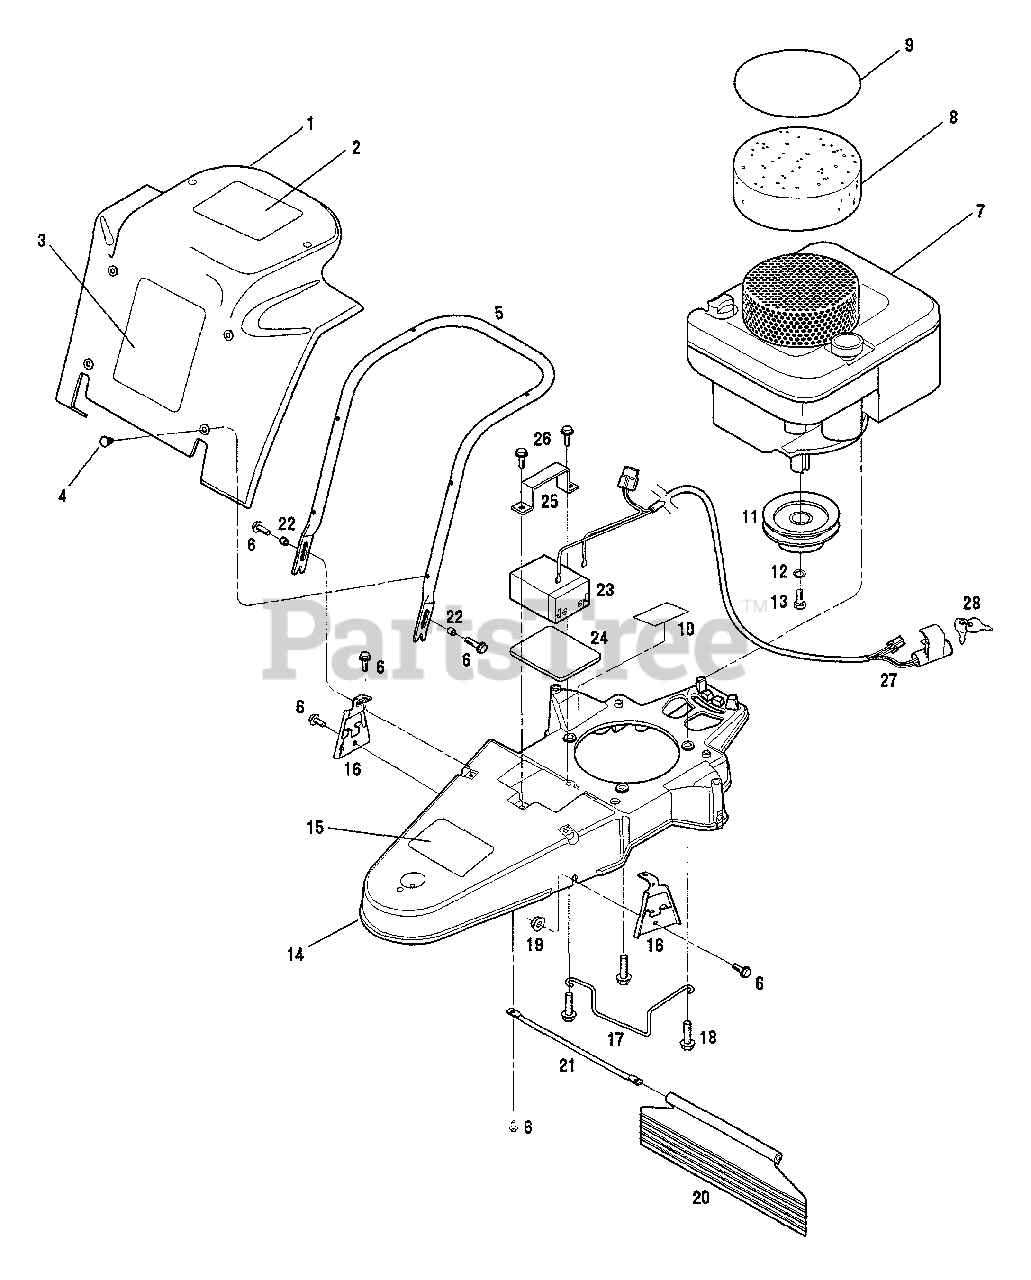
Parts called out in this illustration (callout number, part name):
1	Debris Shield
2	Decal - Parallel Trimmer Instructions
3	Decal - Logo
4	Push-in Fastener
5	Debris Guard Support
6	Hex Flange Screw, 1/4-20 x 3/4
7	Engine
8	Engine Foam Debris Guard
10	Decal - Hot Surface Warning
11	Engine Pulley
12	Spring Lock Washer
13	Hex Hd. Screw, 3/8-24 x 1, Grade 5
14	Deck
15	Decal - Warning
16	Hood Bracket
17	Belt Guide
18	Hex Hd. Screw, 3/8-16 x 1-1/2
19	Flange Locknut, 1/4-20
20	Deflector Flap
22	Spacer
23	Battery
24	Battery Pad
25	Battery Clamp
26	Hex Flange Screw, 5/16-18 x 1
27	Wire Harness
28	Ignition Key
